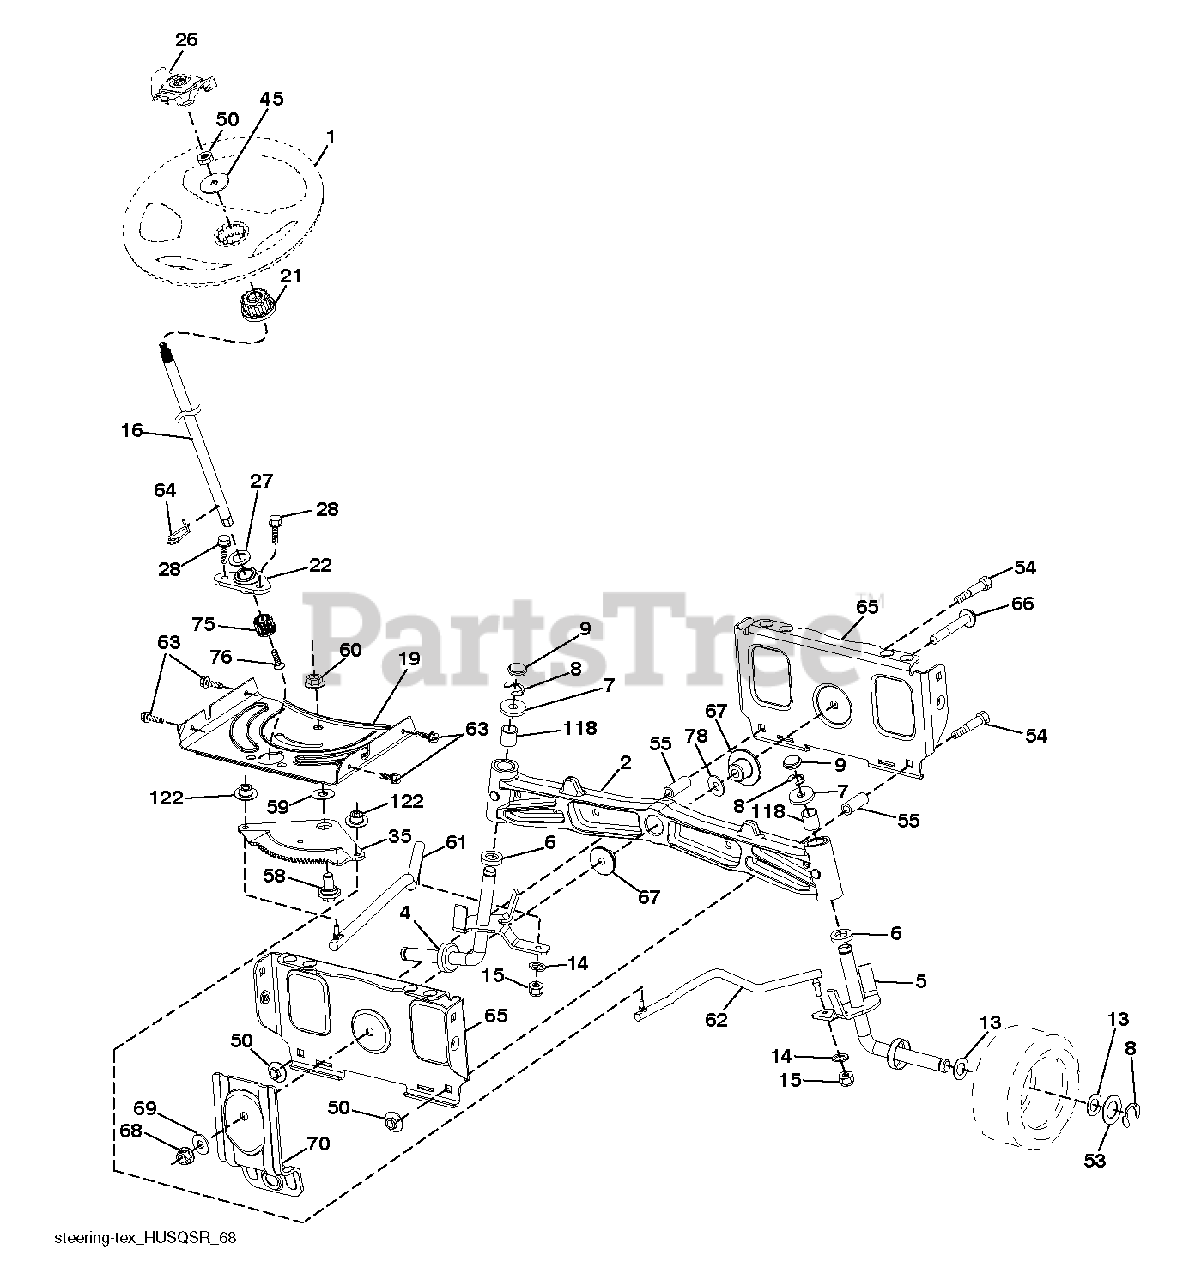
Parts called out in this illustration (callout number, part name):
1	WHEEL.STEER.HUSQ.SR.498.OVMLD
2	AXLE.SVC.ASM CAST IRON.TEX
4	SPINDLE.WELDED.LH.16"TEX
5	SPINDLE.WELDED.RH.16"TEX
6	THRUST WASHER
9	CAP.SPINDLE.BLACK
14	WASHER, LOCK 3/8
15	NUT CROWNLOCK 3/8-24
16	SHAFT.STEER.2HIGH.SPLND.PLATED
19	PLATE.STEER.DDL.NLT/NG
21	ADAPTER.WHEEL.STEER.SPLND.ALUM
22	BEARING.SHAFT.STEER.LOWER.625
26	INSERT.CAP.WHL.STRG.HUSQ.PREM
28	SCREW, 3/8-16X3/4
35	GEAR.SECTOR.PLATE.DDL.
45	WASHER.3/8ID.2-3/8OD.12GA.PLTD
50	NUT LOCK FLG 3/8-16 UNC
53	WASHER.HARDENED
55	SPACER.BRACE.AXLE
58	BOLT.SHOULDER.SECTOR.P
59	WASHER.THURST.SECTOR.S
60	NUT FLANGE LOCK 5/8-11
61	DRAGLINK.LH.ADJUSTABLE.TEX
62	DRAGLINK.RH.ADJUSTABLE.TEX
63	SCREW
64	RETAINER.CLIP.SPRING.S
65	BRACE.AXLE.FRONT.NLT/N
66	BOLT HEX FGHD 7/16-14 X 3 SERR
67	BUSHING.PM.FRONT AXLE
68	NUT.LOCK.FLANGE.7/16
69	WASHER.1.5X.505X.118
70	BRACKET.FRT.DECK.SUSP.RR.MT431
75	PINION.ZINC PLATED
76	SCREW HEAD SOCKET LRVB
78	THRUST WASHER
118	BUSHING, AXLE CAST
122	CAP.GEAR.SECTOR.TEX
